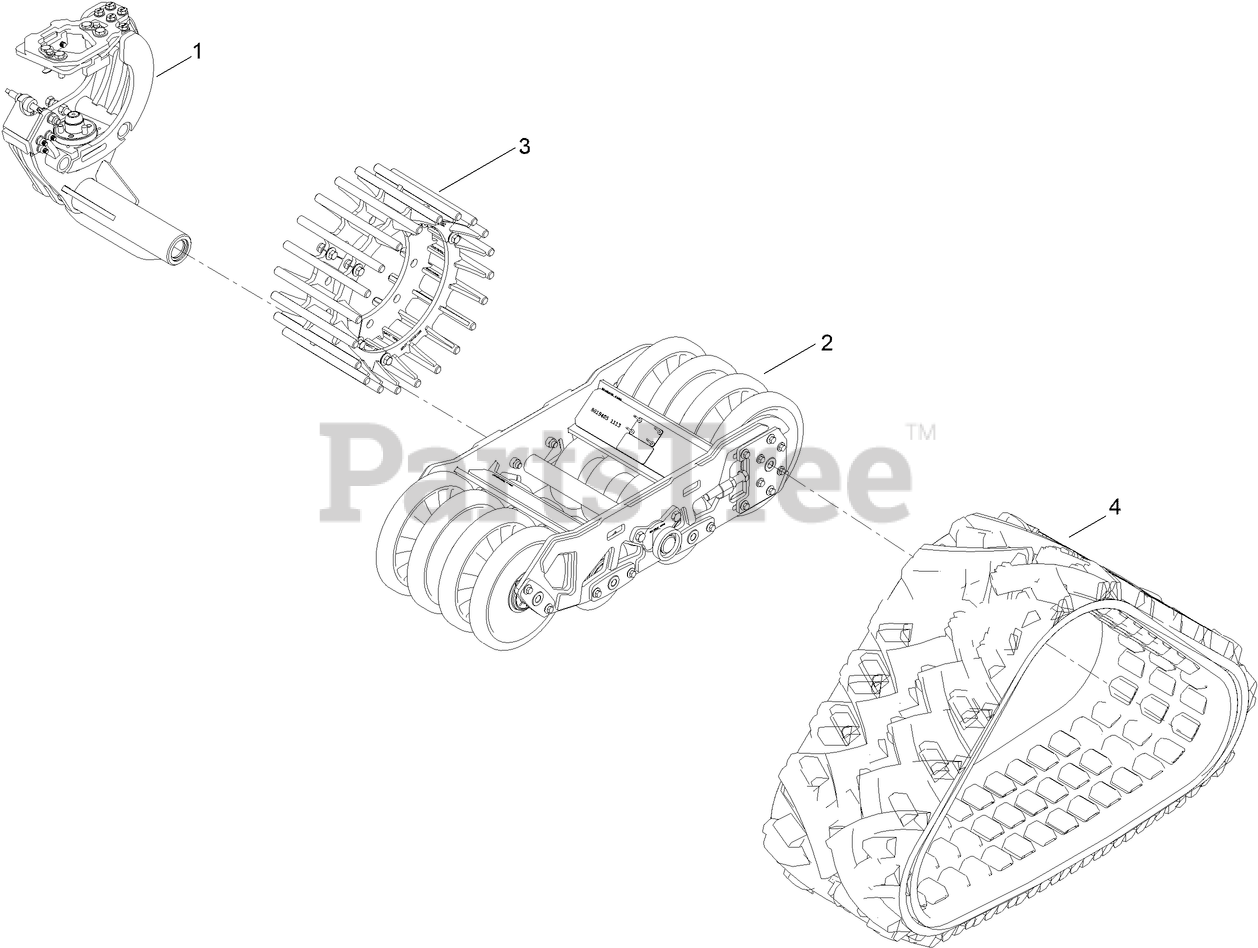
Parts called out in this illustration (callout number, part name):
2	CHASSIS ASSEMBLY
3	SPROCKET ASM-21 TOOTH
4	TRACK-RUBBER, 511E, 19.5 IN
